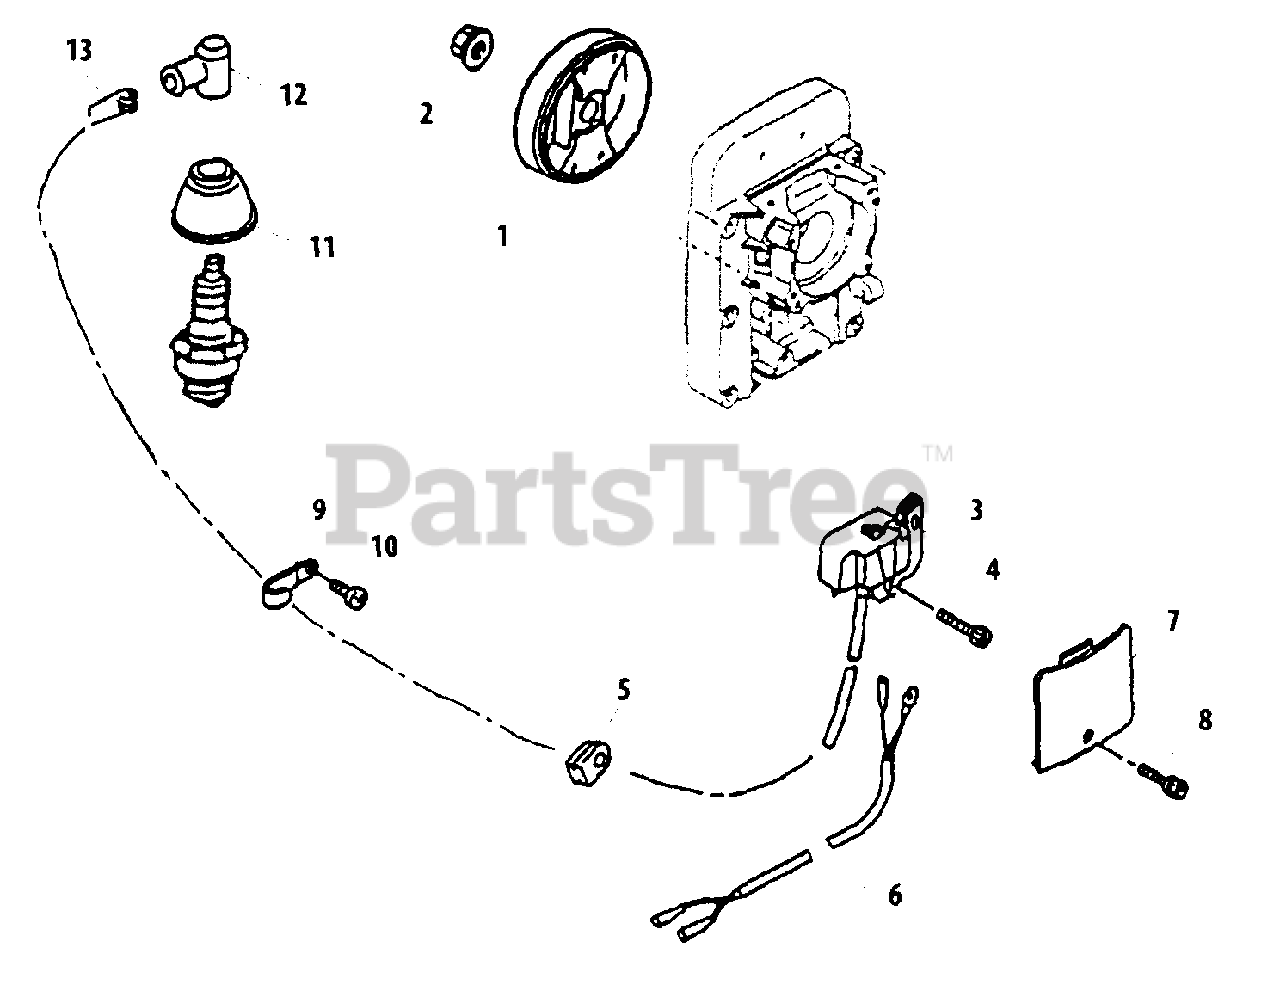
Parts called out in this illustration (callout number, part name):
1	FLYWHEEL
2	NUT - 10 -- FLANGE
3	COIL, IGNITION
4	SCREW - 4X20
5	GROMMET
6	LEAD ASSY
8	BOLT - 4X16
9	CLAMP
10	SCREW - 5X14 -- TAPPING
11	COVER, SPARK PLUG CAP
12	CAP, SPARK PLUG
13	TERMINAL, SPARK PLUG CAP
